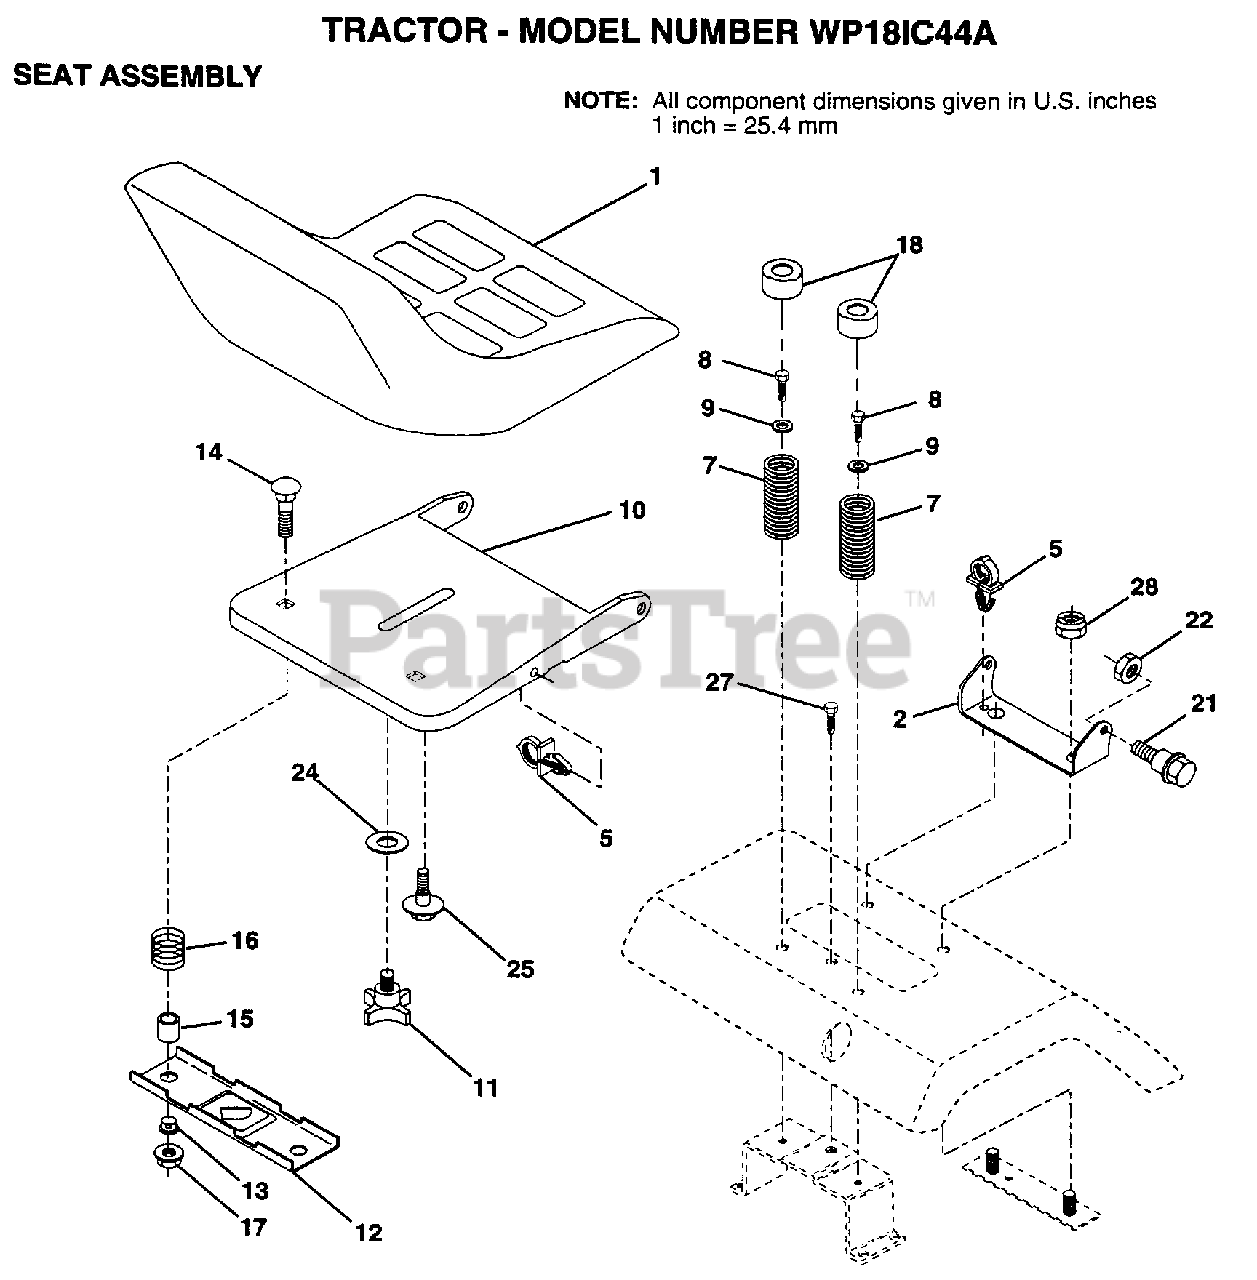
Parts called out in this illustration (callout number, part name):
2	BRACKET PVT SEAT
5	CLIP.PUSH-IN.HING
7	SPRING COMPRESSIO
8	SCREW LT
9	WASHER
11	"KNOB 1/2"" YT"
12	BRKT SWITCH
13	BUSHING
15	SPACER SPLIT
16	SPRING COMPRESSED
18	CAP SPRING
21	BOLT.SHLD.5/16-18
24	WASHER
25	"BOLT,SHOULDER"
27	SCREW LT
